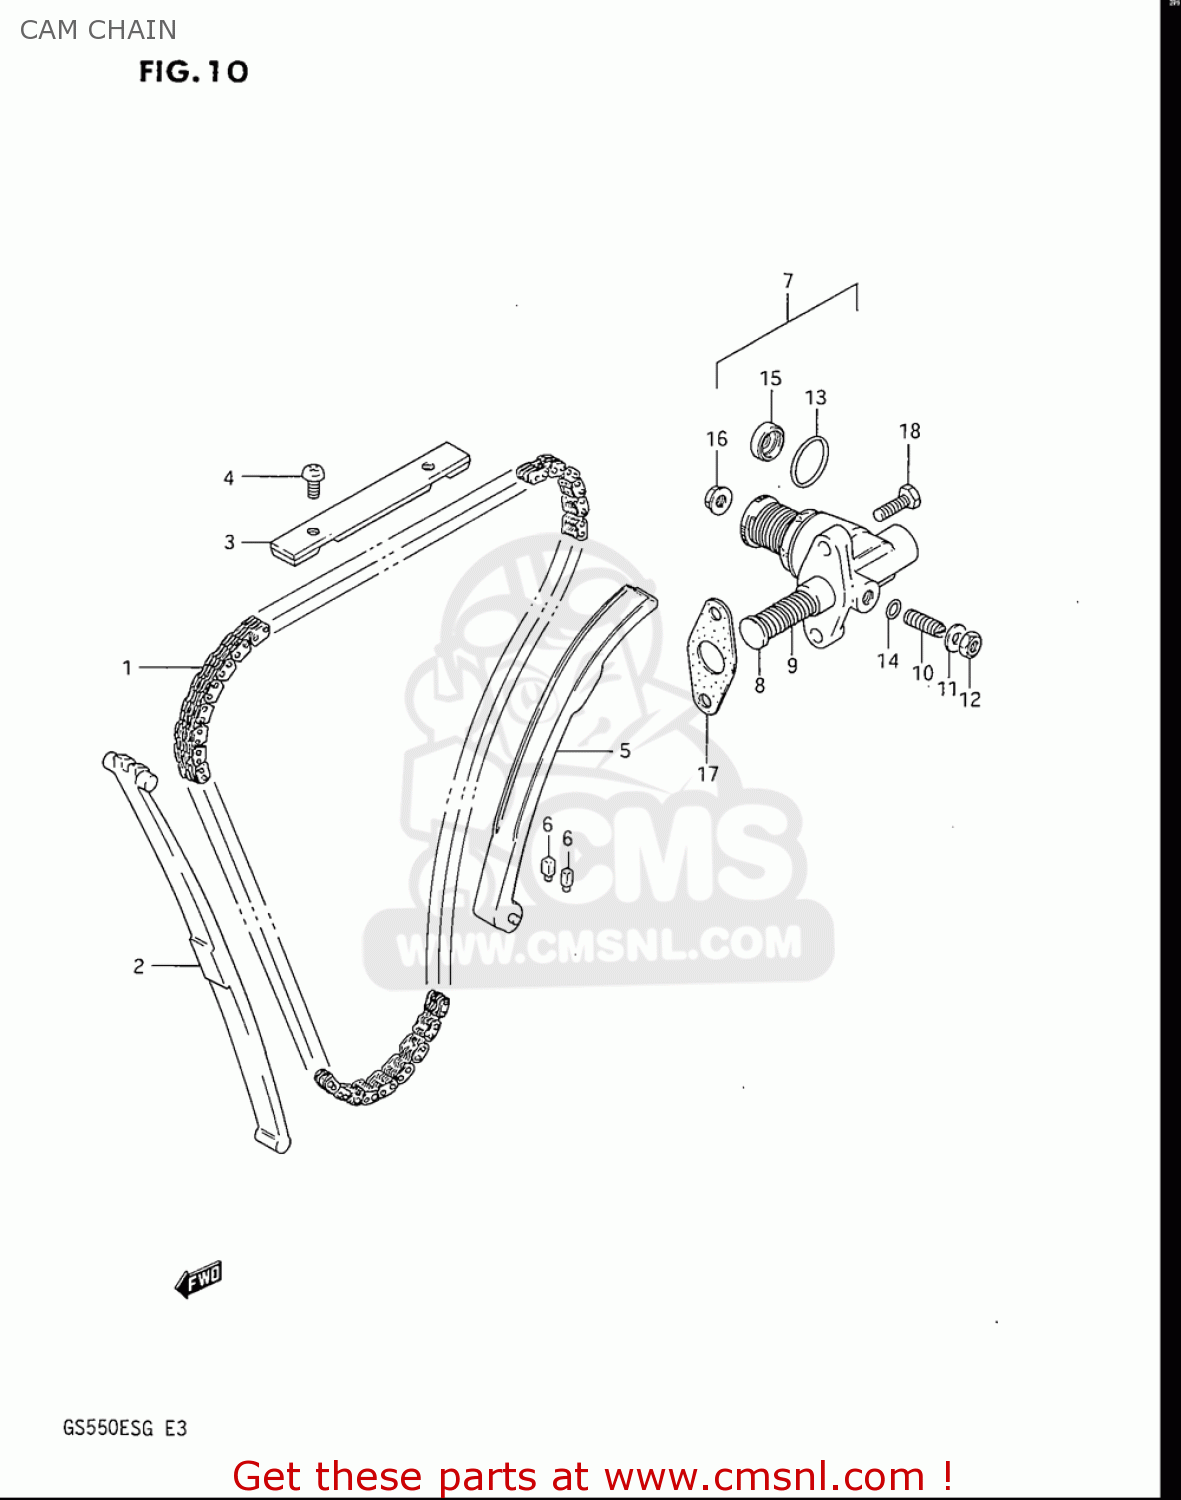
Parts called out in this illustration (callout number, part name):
1	CHAIN,CAMSHAFT DRIVE
2	GUIDE,CAM CHAIN NO.1
3	GUIDE,CAM CHAIN NO.2
4	SCREW
5	TENSIONER,CAM CHAIN
6	CUSHION,CAM CHAIN TENSIONER
7	ADJUSTER ASSY,TENSIONER
10	SCREW
11	WASHER
12	NUT
13	O RING(D:2.4,ID:20.8)
14	O RING(D:1.9,ID:5.7)
15	SEAL,OIL(10X16X4)
16	NUT
17	GASKET,TENSIONER ADJUSTER (NAS)
18	SCREW (6X25)
